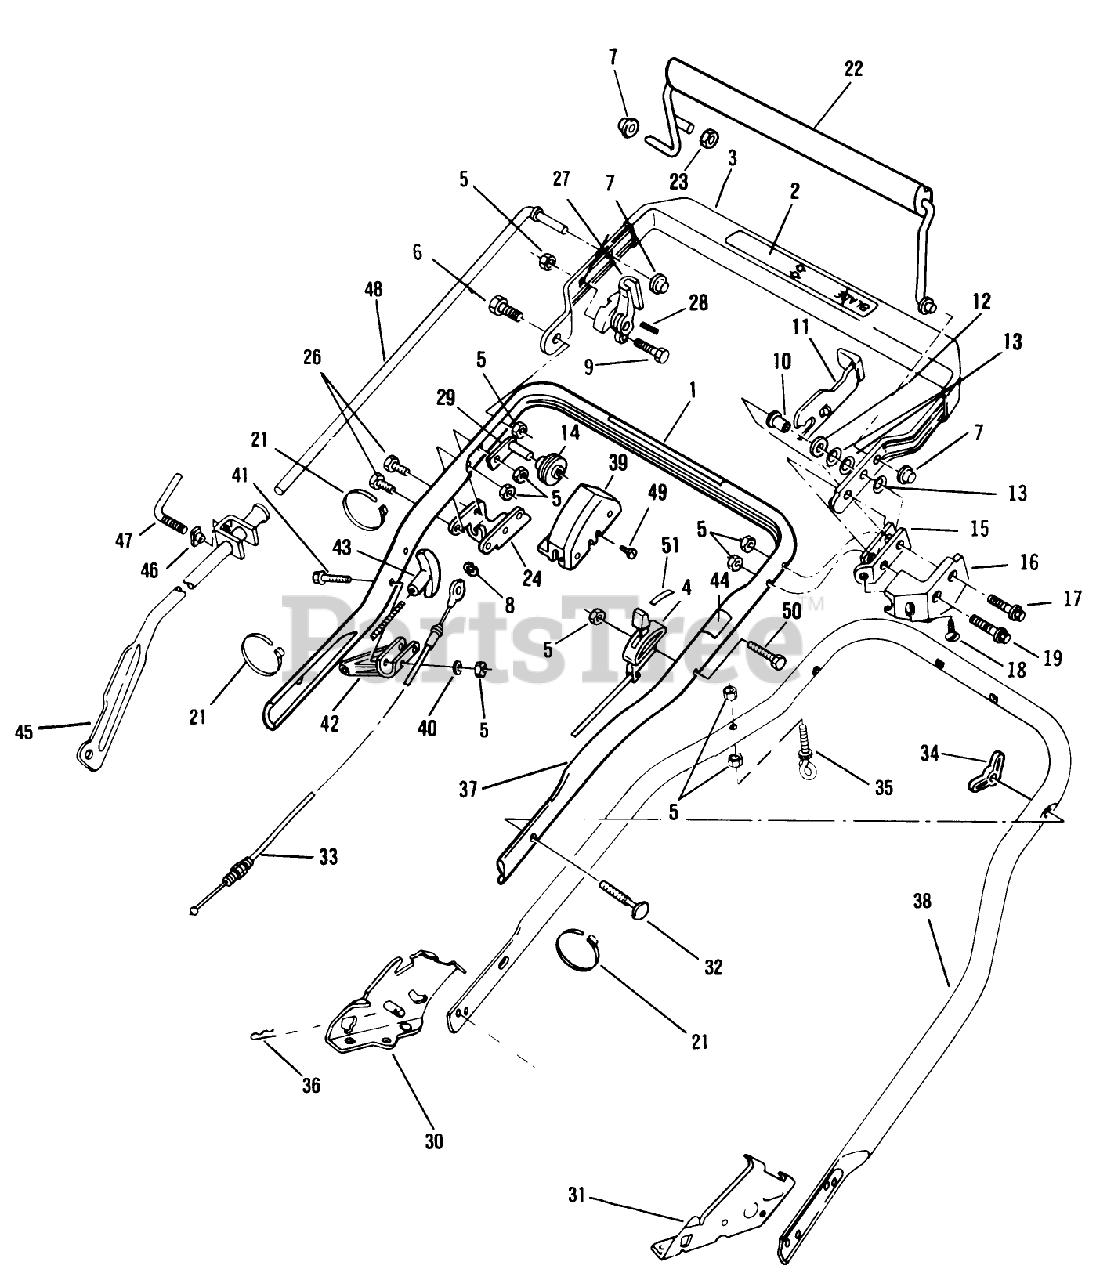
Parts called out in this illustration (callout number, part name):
4	CONTROL THROT WES
5	LOCKNUT E
6	BOLT
8	RET. RING
10	SPACER
12	WASHER M
14	PULLEY PL
15	DOWN STOP
16	LOCKOUT GUARD
17	BOLT SHOU
18	SCREW F
19	SCREW
23	NUT ACORN
30	BRACKET ASM - HANDLE, SP, RH
31	BRACKET ASM - HANDLE, SP, LH
32	BOLT QUALITY
33	CONTROL CABLE
34	NUT-WING
35	EYE BOLT WAS MFG
36	HAIR PIN
37	HANDLE SECTION
40	WASHER
43	HANDLE START UM&D
45	CONTROL LEVER AY
48	CONTROL ROD
